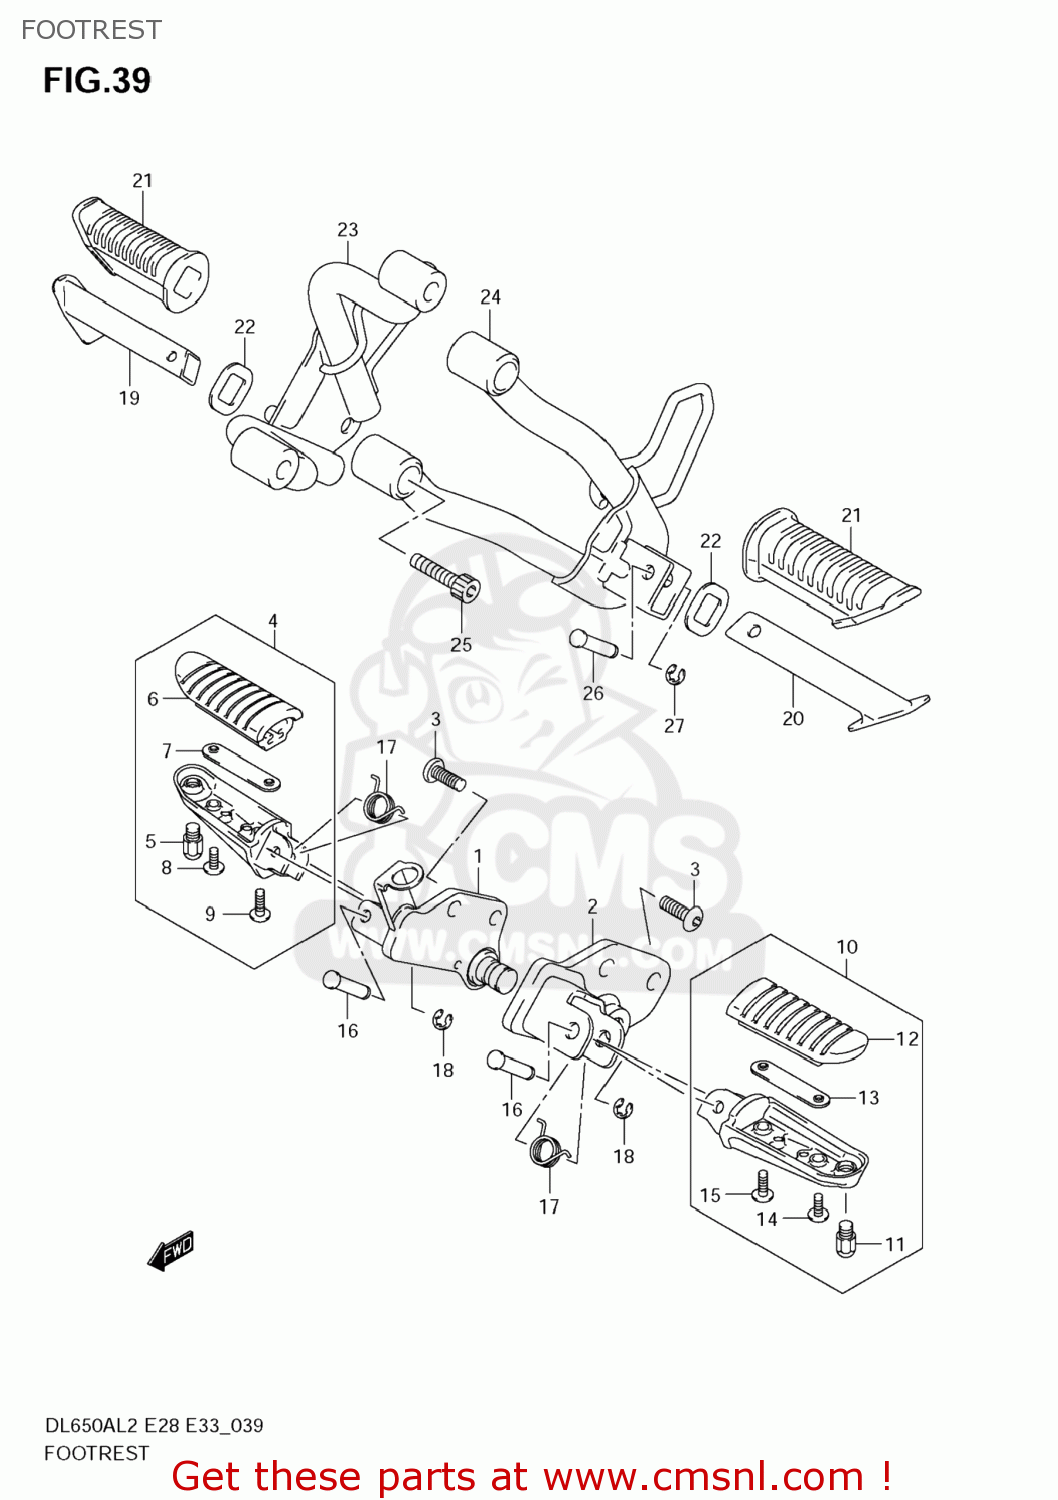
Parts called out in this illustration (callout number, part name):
1	BRACKET,FR FOO
2	BRACKET,FR FOO
3	BOLT(8X23)
4	FOOTREST ASSY,PILLION,R
5	BOLT,BANK SENSOR
6	RUBBER,FOOTREST
7	PLATE,FR FOOTREST RUBBER
8	SCREW
9	SCREW
10	FOOTREST ASSY,PILLION,L
11	BOLT,BANK SENSOR
12	RUBBER,FOOTREST
13	PLATE,FR FOOTREST RUBBER
14	SCREW
15	SCREW
16	PIN(8X33.2)
17	SPRING
18	E RING
19	BAR,PILLION FOOTREST,R
20	BAR,PILLION FOOTREST,L
21	RUBBER,PILLION FOOTREST
22	WASHER,FOOTREST RUBBER
23	BRACKET,PILLION FOOTREST,R
24	BRACKET,PILLION FOOTREST,L(BLA
25	BOLT(8X40)
26	PIN(6X29.5)
27	E RING
